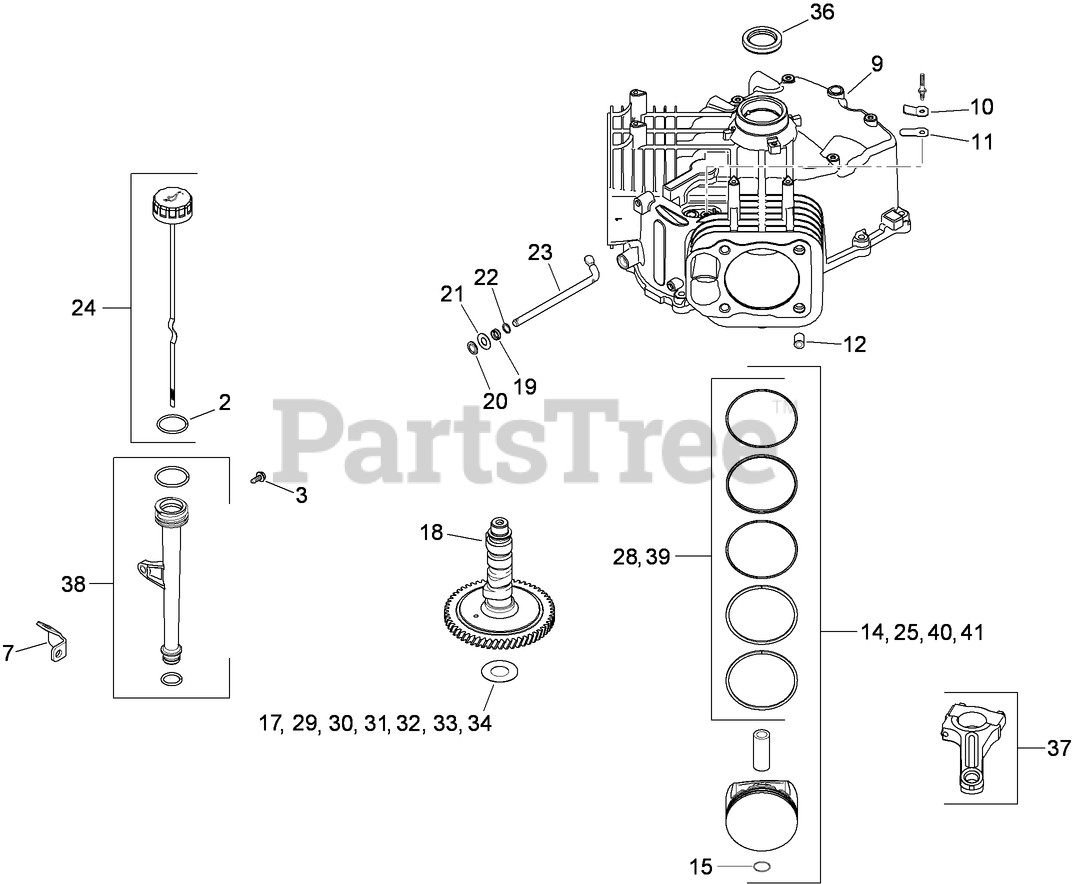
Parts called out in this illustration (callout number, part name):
2	O-RING
3	SCREW-FLG, THD FRM (M5X0.8X13)
7	BRACKET-TUBE, OIL FILL
9	SHORTBLOCK (SV710-740)
10	RETAINER-REED, BREATHER
11	REED-BREATHER
12	Pin-Locating
14	PISTON W/RING SET (STD) (INCLUDES REF 8, 17)
15	RETAINER-PIN, PISTON
17	SHIM-CAMSHAFT (WHITE .028)
18	CAMSHAFT KIT (INCLUDES 25 357 14-S)
19	SEAL-CROSS SHAFT, GOVERNOR
20	RETAINER-RING
21	WASHER-FLAT (9MM)
22	WASHER-FLAT (11/32)
23	SHAFT-CROSS, GOVERNOR
24	Dipstick ASM (Includes 2)
25	PISTON W/RING SET (.25) (INCLUDES REF 8, 19)
28	PISTON RING SET (.25)
29	SHIM-CAMSHAFT (BLUE .03)
30	SHIM-CAMSHAFT (RED .032)
31	SHIM-CAMSHAFT (YELLOW .034)
32	SHIM-CAMSHAFT (GREEN .036)
33	SHIM-CAMSHAFT (GRAY .038)
34	SHIM-CAMSHAFT (BLACK .04)
36	SEAL-OIL (HELIX LIP)
37	ROD-CONNECTING (STD)
38	DIPSTICK TUBE ASM
39	PISTON RING SET (STD)
40	PISTON W/RING SET (.08)
41	PISTON W/RING SET (.08) (USE 25 874 02-S KIT)
